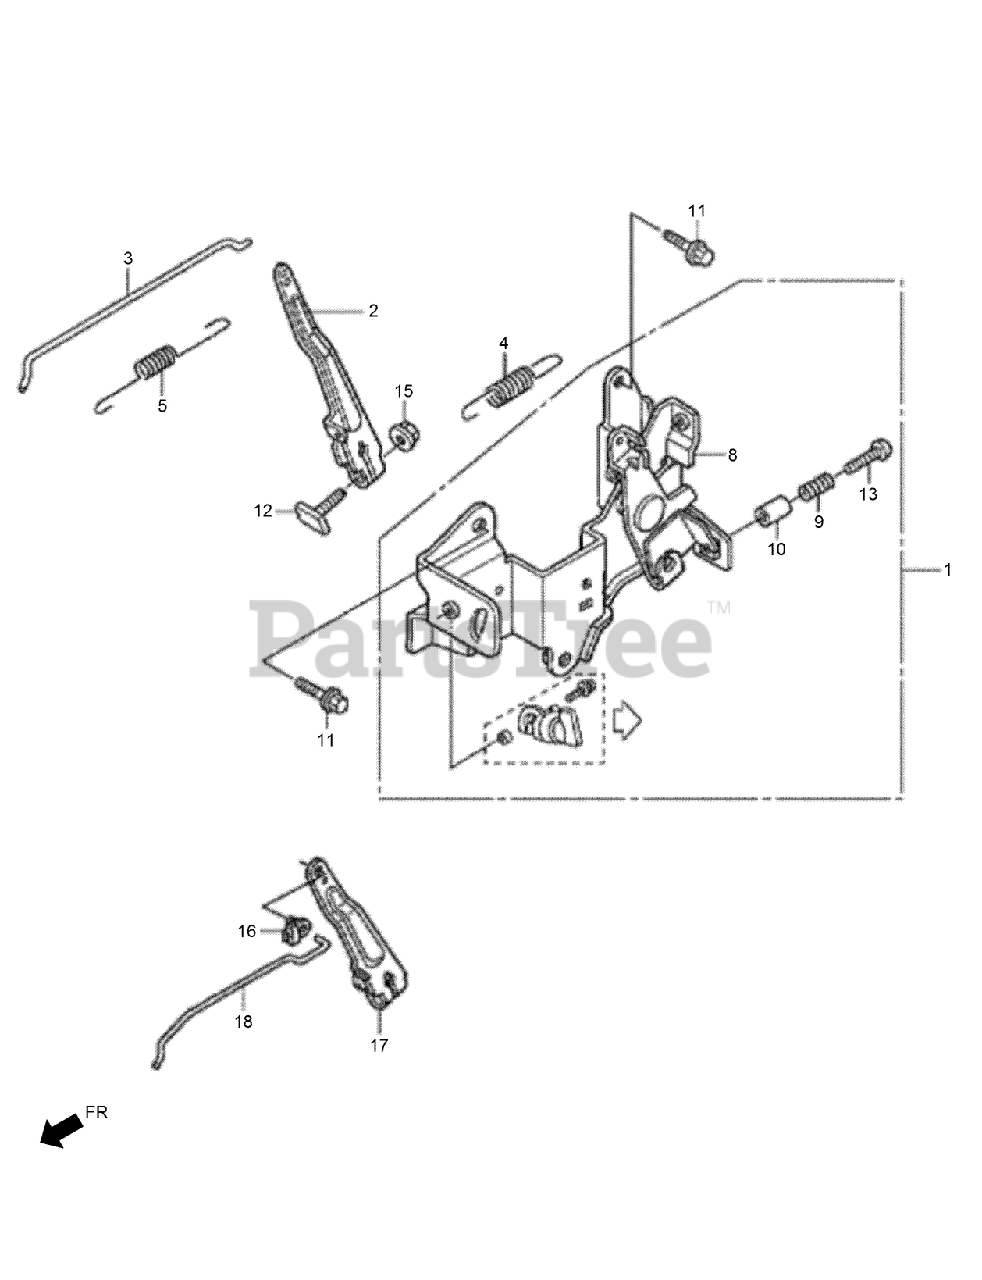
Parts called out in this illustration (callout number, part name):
1	CONTROL ASM
2	ARM-GOVERNOR
3	ROD-GOVERNOR
4	SPRING-GOVERNOR
5	SPRING-THROTTLE RETURN
8	CONTROL BASE ASM
9	SPRING-CONTROL ADJUSTING
10	COLLAR-STOPPER
11	BOLT-FLANGE-5X12
12	BOLT-GOVERNOR ARM
13	SCREW-RECESSED-5X28
15	NUT-FLANGE-6MM
16	JOINT-ROD
17	ARM-GOVERNOR
18	ROD-GOVERNOR
